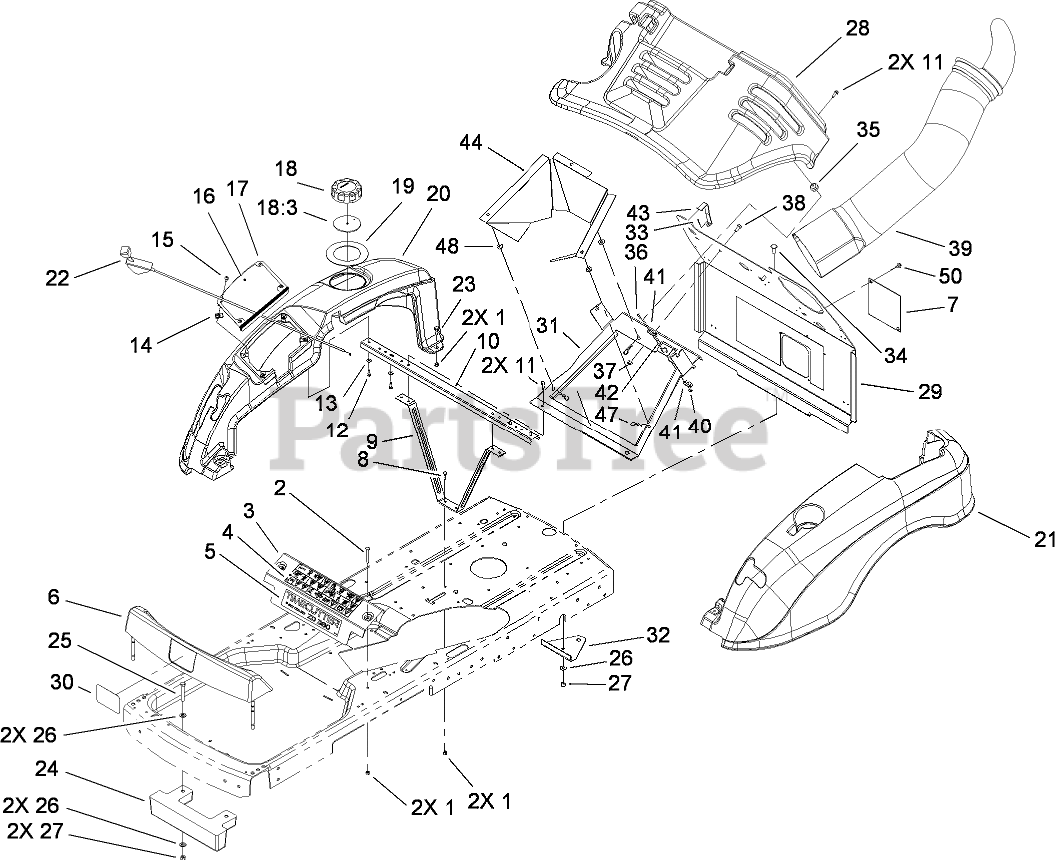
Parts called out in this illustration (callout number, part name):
1	NUT-LOCK, NI
2	SCREW-CARR
3	BRACKET-SUPPORT, FRONT
4	DECAL-DANGER
6	FOOTREST ASM
7	DOOR-PLUG ACCESS
8	SCREW-HH
9	BRACE ASM
10	CHANNEL-CROSS
11	SCREW-HWH, THREAD ROLL
12	SCREW-PLASTITE
13	WASHER-FLAT
15	SCREW-PRH
16	DECAL-CONTROL
17	PANEL-CONTROL
18	GAS CAP ASM
18:3	GASKET-CAP, GAS
19	SEAL-RUBBER
20	COVER-SIDE, RH
21	COVER-SIDE, LH
22	CABLE-THROTTLE
23	SCREW-SHOULDER
24	WEIGHT-BAGGER
25	SCREW-HH
26	WASHER-FLAT
27	NUT-LOCK, NI
28	COVER-ENGINE
29	SHIELD-HEAT, BAG
31	OFFSET HINGE ASM
32	HITCH-TRAILER
33	PIN-COTTER
34	SCREW-CARR
35	GROMMET
36	SCREW-HSBH
37	NUT-LOCK, NI
38	SCREW-HH
39	TUBE-DISCHARGE
40	NUT-LOCK, NI
42	PIN-HOOD
43	TAB-SWITCH
44	DUCT-FAN, ENGINE
47	PIN-HAIR
48	WASHER-RUBBER
50	SCREW-HHFTF
